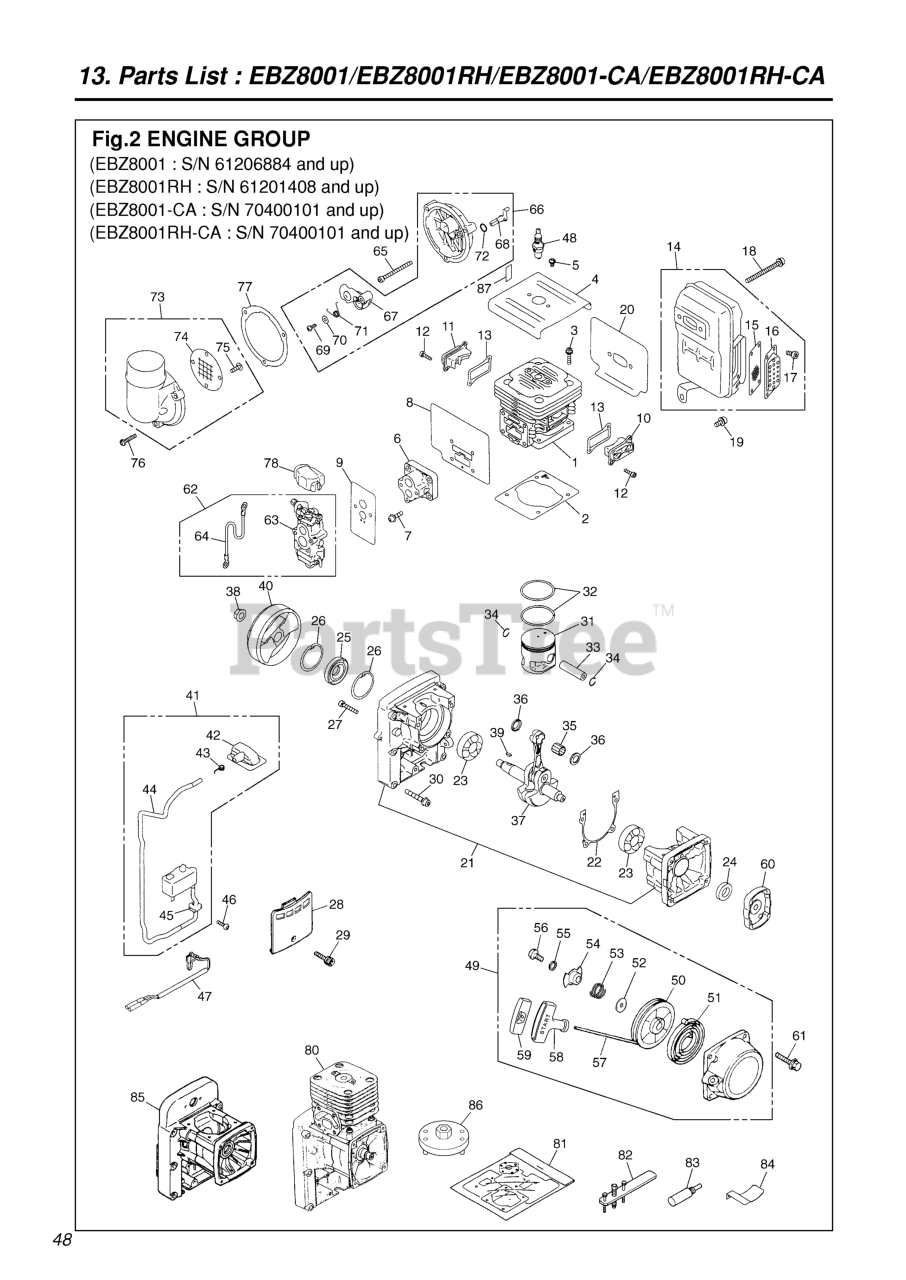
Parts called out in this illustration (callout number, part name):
1	CYLINDER (RPLS 12A2)
2	GASKET, BASE
3	BOLT
4	PLATE, CYL
5	SCREW TORX
6	INSULATOR
7	BOLT
8	GASKET, INSULATOR
9	GASKET, CARB.
10	COVER, TR-S
11	COVER,TR-F
12	BOLT TORX
13	GASKET, TR
14	Muffler Assy
15	Arrester
16	Diffuser
17	Bolt
18	BOLT TORX
19	BOLT
20	GASKET, MUFFLER (RPLS. -15C0)
21	CRANKCASE-CASE
22	GASKET, CASE
23	BEARING
24	SEAL
25	SEAL
26	SNAP RING
27	BOLT
28	COVER
29	BOLT TORX
30	BOLT TORX
31	PISTON
32	RING
33	PIN
34	SNAP RING
35	BEARING
36	WASHER
37	CRANKSHAFT-C
38	NUT, M10
39	KEY
40	ROTOR
41	COIL ASSY
42	CAP
43	SPRING
44	TUBE
45	GROMMET
46	BOLT TORX
47	CORD-C
48	SPARK PLUG
49	RECOIL ASSY (RPLS -7511)
50	REEL (REPLACES -75C1)
51	SPRING
52	WASHER (REPLACES -75M0)
53	SPRING, FRICTION (RPLS. -75L1)
54	PLATE, FRICTION (RPLS. -75K1)
55	WASHER (REPLACES -75W0)
56	SCREW
57	ROPE
58	KNOB
59	COVER KNOB
60	PULLEY (RPLS 848-H00-7520)
61	BOLT, TORX
62	CARBURETOR SET
63	CARBURETOR-A (WYA-44)
64	Cord
65	BOLT
66	CUP ASSY
67	PLATE, CHOKE
68	LEVER
69	SCREW
70	WASHER
71	SPRING
72	O-RING
73	COVER ASSY. (REPLACES -8340)
74	SCREEN
75	SCREW
76	SCREW
77	GASKET,CUP
78	COVER
80	SHORT BLOCK (EBZ8000)
81	GASKET KIT
82	PULLER ASSY
83	STOPPER (TOOL)
84	GAUGE
85	CRANKCASE-A
86	PULLER
87	LABEL, CHOKE
